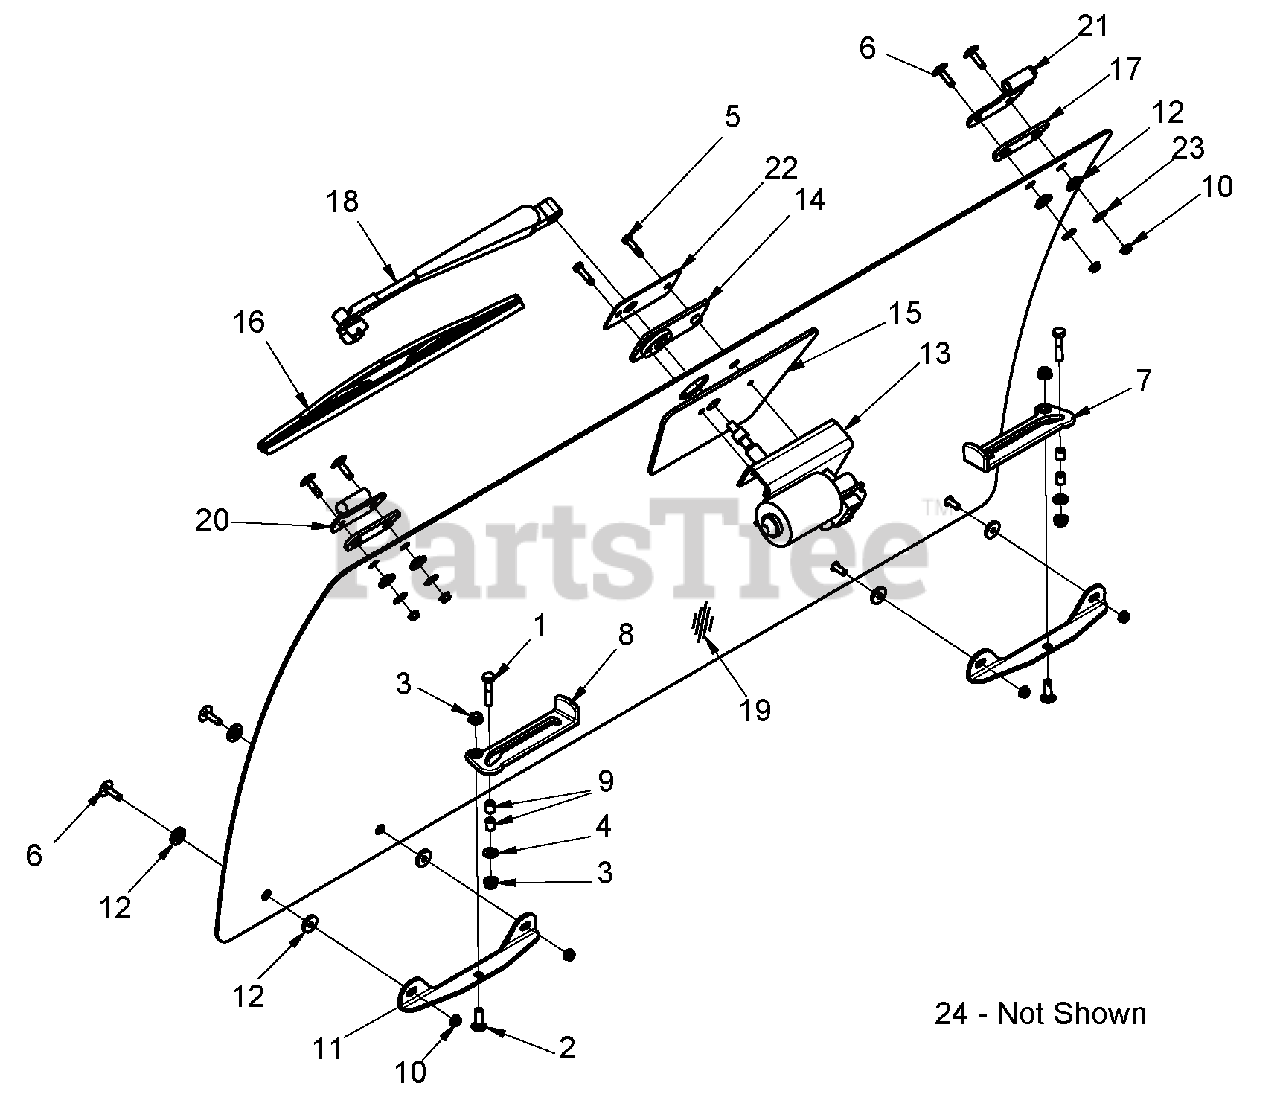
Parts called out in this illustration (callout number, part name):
1	Bolt, Hex .31-18 x 1.50 Grade 5
2	Bolt, Round Head Square Neck .31-18 x 1 Grade 5
3	Nut, .31-18 Nyloc Flange
4	Washer, Flat 5/16
5	Bolt, Wiper Motor
6	Bolt, Step 1/4 x 1 Black
7	Handle, Right Window
8	Handle, Left Window
9	Bushing, Latch
10	Nut, Flange 1/4 Black
11	Plate, Window Latch
12	Bushing, 5MM Black Neoprene
13	Motor, Front Wiper
14	Bushing, Outer Wiper
15	Bushing, Inner Wiper
16	Blade, 18" Wiper
17	Neoprene, Hinge
18	Arm, 14" Radial Wiper
19	Glass, Front Window
20	Assembly, Left Hinge
21	Assembly, Right Hinge
22	Plate, Wiper Mount
23	Flat Washer
24	Front Window Weather Stripping
